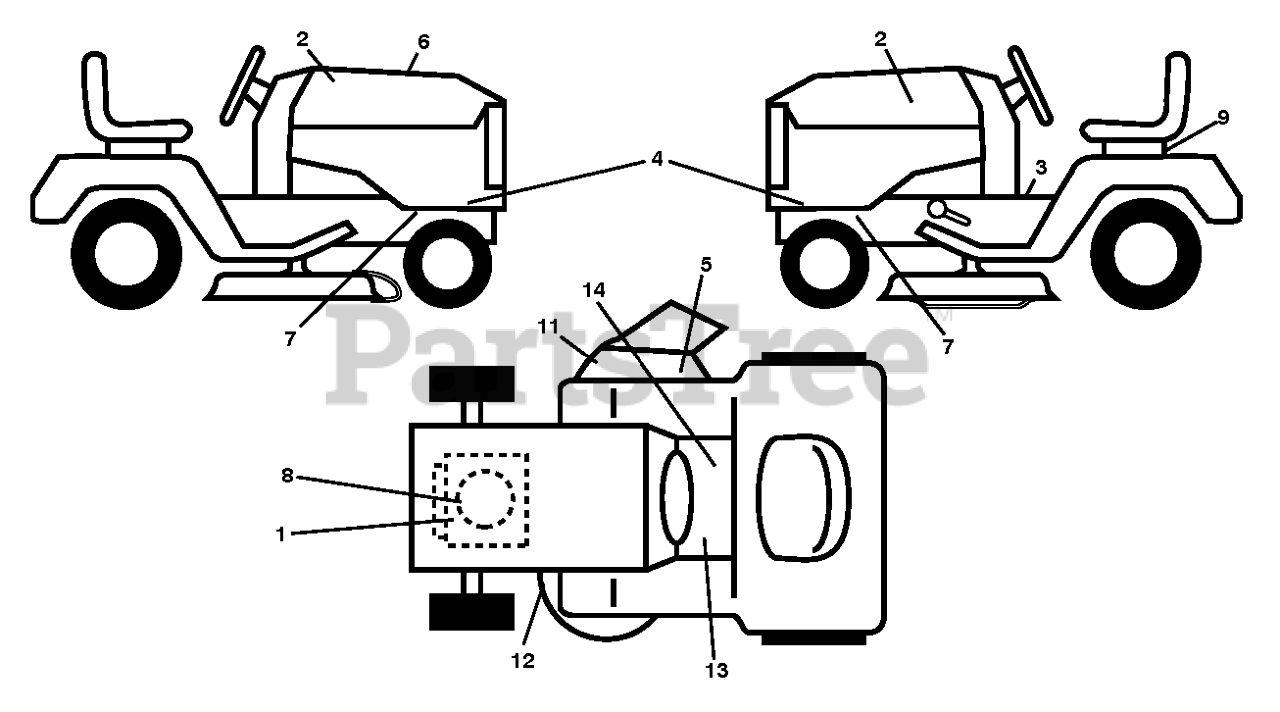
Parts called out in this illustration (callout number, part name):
1	DECAL.ENGINE.WARNING
2	DECAL.BADGE.170MM.TEXTLOGO.
3	DECAL.READ.OWN.MAN.SYMBOL.LT
7	DECAL.CHASSIS.HOT.MUFFLER
8	DECAL
9	DECAL BTRY SYMBOLS
11	DECAL.WARN.DFLCTR/CTFNGR.SRD.
12	DECAL.V.BELT.30"
13	DECAL.FNDR.SDLE.BRAKE.CLUTCH.6
14	DECAL.PARKING.BRAKE.SADDLE.LT
